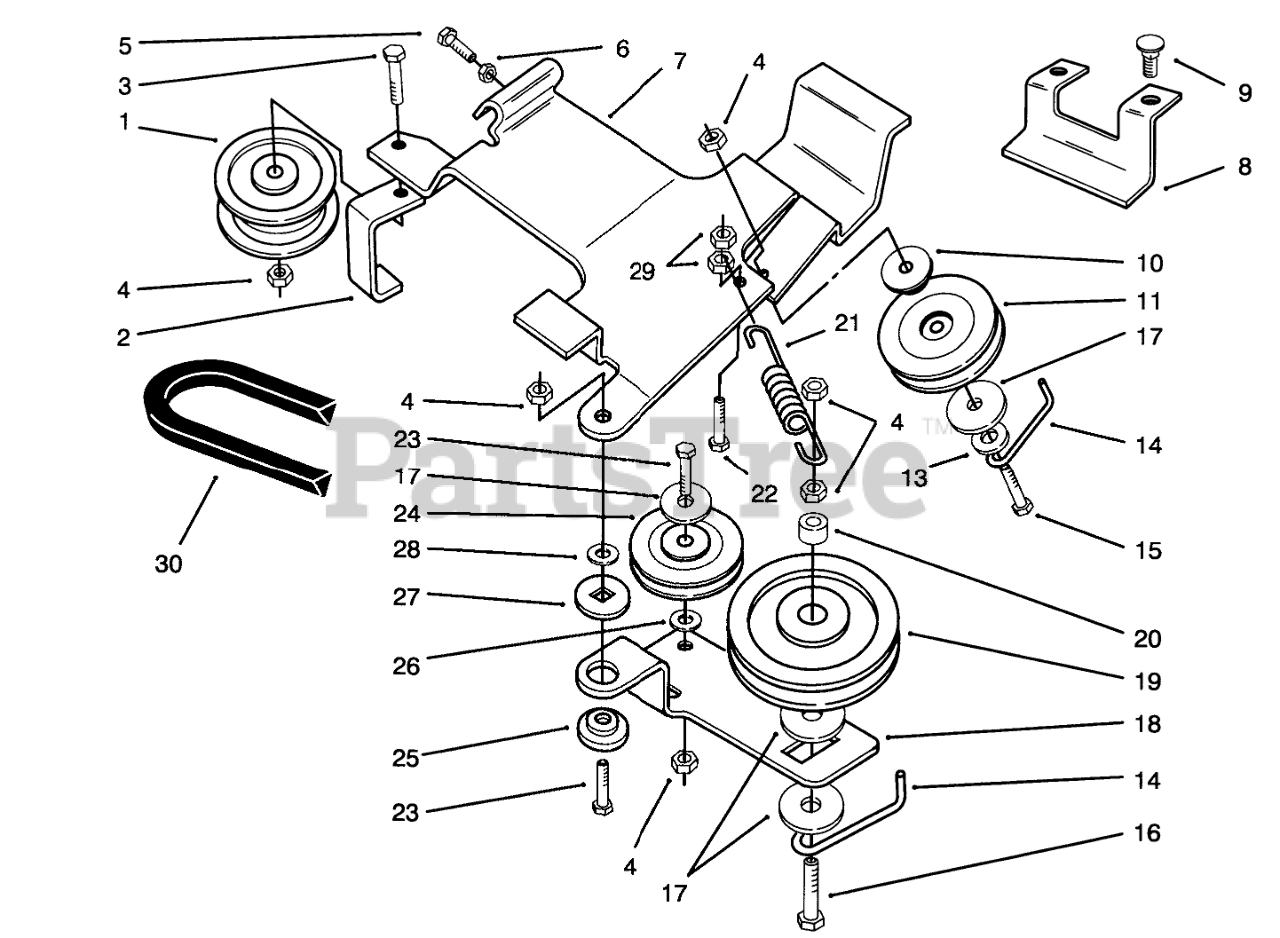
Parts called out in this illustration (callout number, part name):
1	Pulley
2	GUIDE-BELT
3	SCREW-HH
4	NUT-LOCK, NI
5	SCREW-HEX HD
6	NUT-JAM
7	RACK-TILLER DRIVE
8	BRACKET - RACK MOUNTING
9	BOLT-CARR
10	SPACER
11	PULLEY-IDLER
13	WASHER-FLAT
14	GUIDE-BELT
15	SCREW-HH
16	SCREW-HH
17	Washer
18	ARM-IDLER
19	PULLEY-IDLER, FLAT
20	SPACER-PIVOT
21	SPRING-EXTENSION
22	SCREW-HH
23	SCREW-HH
24	PULLEY-IDLER
25	BUSHING
26	SPACER
27	WASHER-BEARING
28	Washer
29	NUT-LOCK, NI
30	V-BELT
